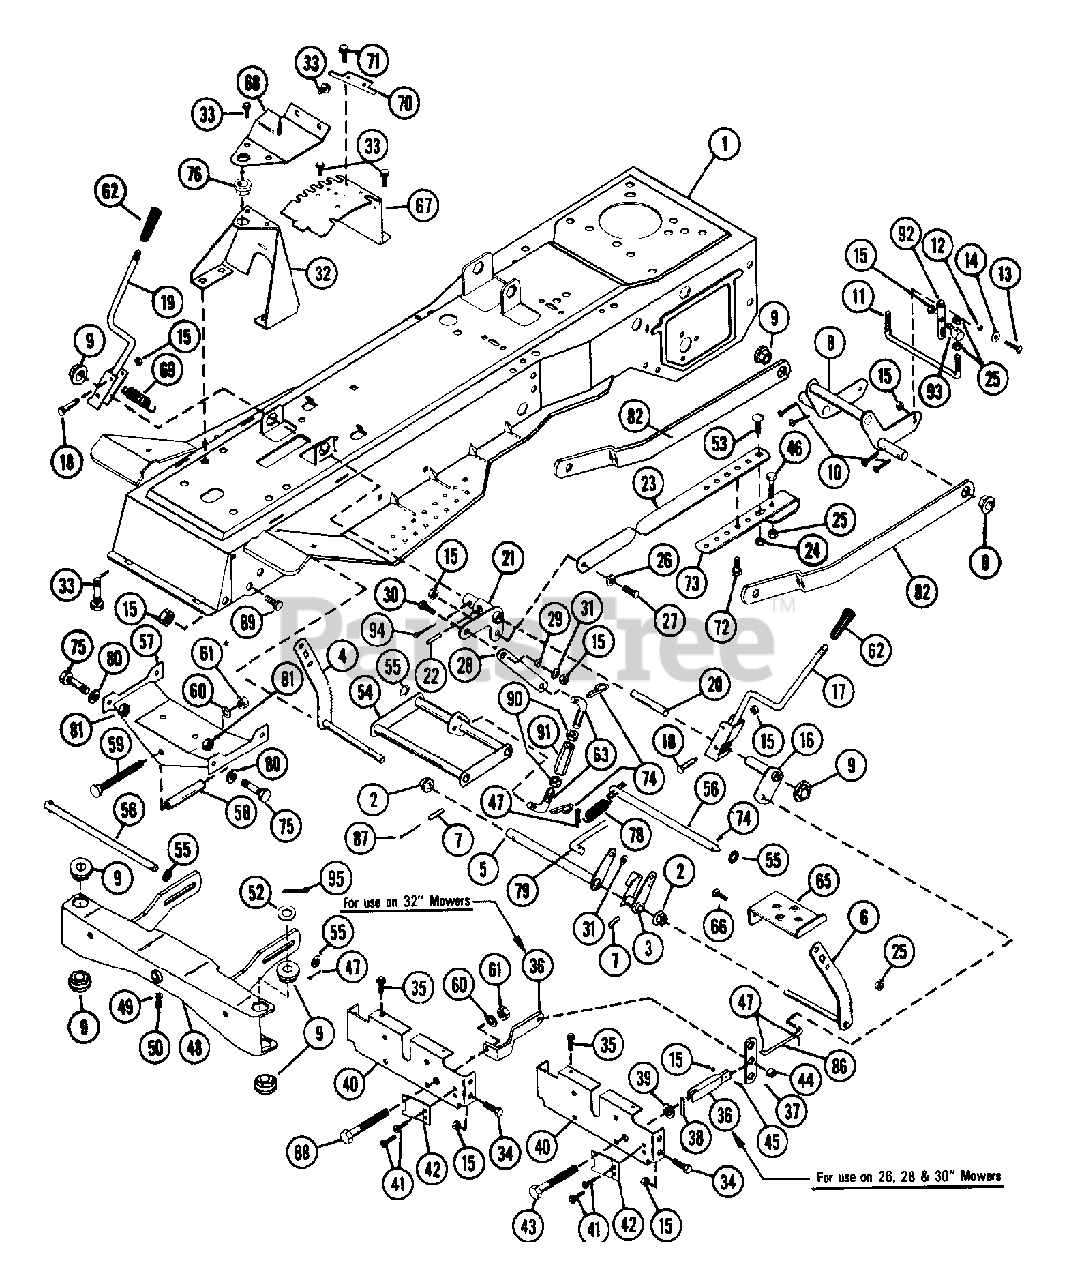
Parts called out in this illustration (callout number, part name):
1	FRAME
2	FLANGE BUSHING
3	CLUTCH ARM
4	BRAKE PEDAL ARM
5	BRAKE ARM
6	CLUTCH PEDAL ARM
7	PIN-ROLL .188X1.00
8	REAR MOWER HANGER
9	FLANGE BUSHING
10	PIN-COTR .09X1.0 PL
11	ROD - REAR LIFT
12	SPACER BUSHING .5 X .32 X .21
13	SCR-SKH .31-18X.75 BTNHD YWZC
14	WSHR-FL-STL .344X1.125X.063PL
15	NUT-LK .312-18 GR A PL
16	CLUTCH ARM
17	MOWER CLUTCH LEVER
18	SHOULDER BOLT .436 X .912
19	MOWER HEIGHT LEVER
21	MOWER LIFT ARM
22	PIN-ROLL .188X1.25
23	LIFT STRAP
24	NUT-LK-CTR .375-16 GR A PL
25	NUT-LK-JAM-CTR .375-16 PL
26	SPACER -SHLD .344X.500X.469
27	BLT-HEX .31-18X1.25 PL GR2
29	SPACER BUSHING .5 X .32 X .163
30	BLT-HEX .31-18X.75 PL GR2
31	WSHR-FL-STL .323X.625X.062 PL
32	STEERING SUPPORT
33	BLT-SERHFWH .31-18X.50 PL
34	BLT-HEX .31-18X.63 PL GR 2
35	SCR-TAP .250-20X.50 HXSLHDPL
36	ADJUSTMENT YOKE
36	FRONT ANCHOR
37	CLUTCH LINK
38	PIN-ROLL .188X1.00
39	WSHR-FL-STL .505X1.000X.062
40	MOWER ADJUSTMENT BRACKET
41	SCR-TAP 10-24X.25 CRSLPH PL 1A
42	LOCK SPRING
43	CAP SCREW
44	SPACER BUSHING .5 X .32 X .21
44	SPACER BUSHING .5 X .32 X .163
45	BLT-HEX .31-18X.88 PL GR2
46	BLT-HEX .38-16X1.50 PL GR2
47	PIN-COTR .09X.75 PL
48	AXLE
49	WSHR-FL-STL .265X.500X.087 PL
50	SPIN DRIVE ZERK FITTING
52	WSHR-FL-STL .755X1.375X.062 PL
53	BLT-RDHDSQNK .38-16X.75 SHT PL
54	FRONT LIFT ARM
55	WSHR-FL-STL .505X.880X.072 PL
56	HANGER PIN
57	AXLE BRACKET
58	TUBE AXLE PIVOT
59	BLT-HEX .50-13X4.00 PL GR2
60	WSHR-LK .500X.151 HVY PL
61	NUT .50-13 PL
62	HANDLE
63	LINK - FRONT LIFT
66	BLT-RDHDSQNK .38-16X.62 GR5 PL
67	QUADRANT
69	SG-TENS .092X.69X1.75 WLD 54
71	BLT-SERHFWH .25-20X.50 PL
72	BLT-HEX .38-16X.75 PL GR2
73	ADJUSTMENT STRAP
74	PIN-HAIR INT .08X.38X1.42 YWZC
75	BLT-SERRDHD SL .31-18X.75 YZ
76	FLANGE BUSHING
77	NUT .50-13 PL
78	SG-TENS .035X.45X2.75 WLD 3.5
79	BRAKE ROD
80	WSHR-LK .375X.094 MED PL
81	NUT-FLG. .312-18 PL
82	POSITIONING ARM
83	WSHR-LK .500X.151 HVY PL
85	BLT-HEX .50-13X1.25 PL GR2
86	LINK
87	PIN-COTR .09X1.87 PL
88	BLT-HEX .50-13X1.25 PL GR2
89	BLT-HEX .31-18X.50 PL GR2
90	NUT-LK .375-16
91	NUT-CUPLG .375-16 PL
92	LINK - REAR LIFT
93	ROD PIVOT
94	PIN-COTR .18X1.50 PL
95	PIN-COTR .12 X 1.25 PL
